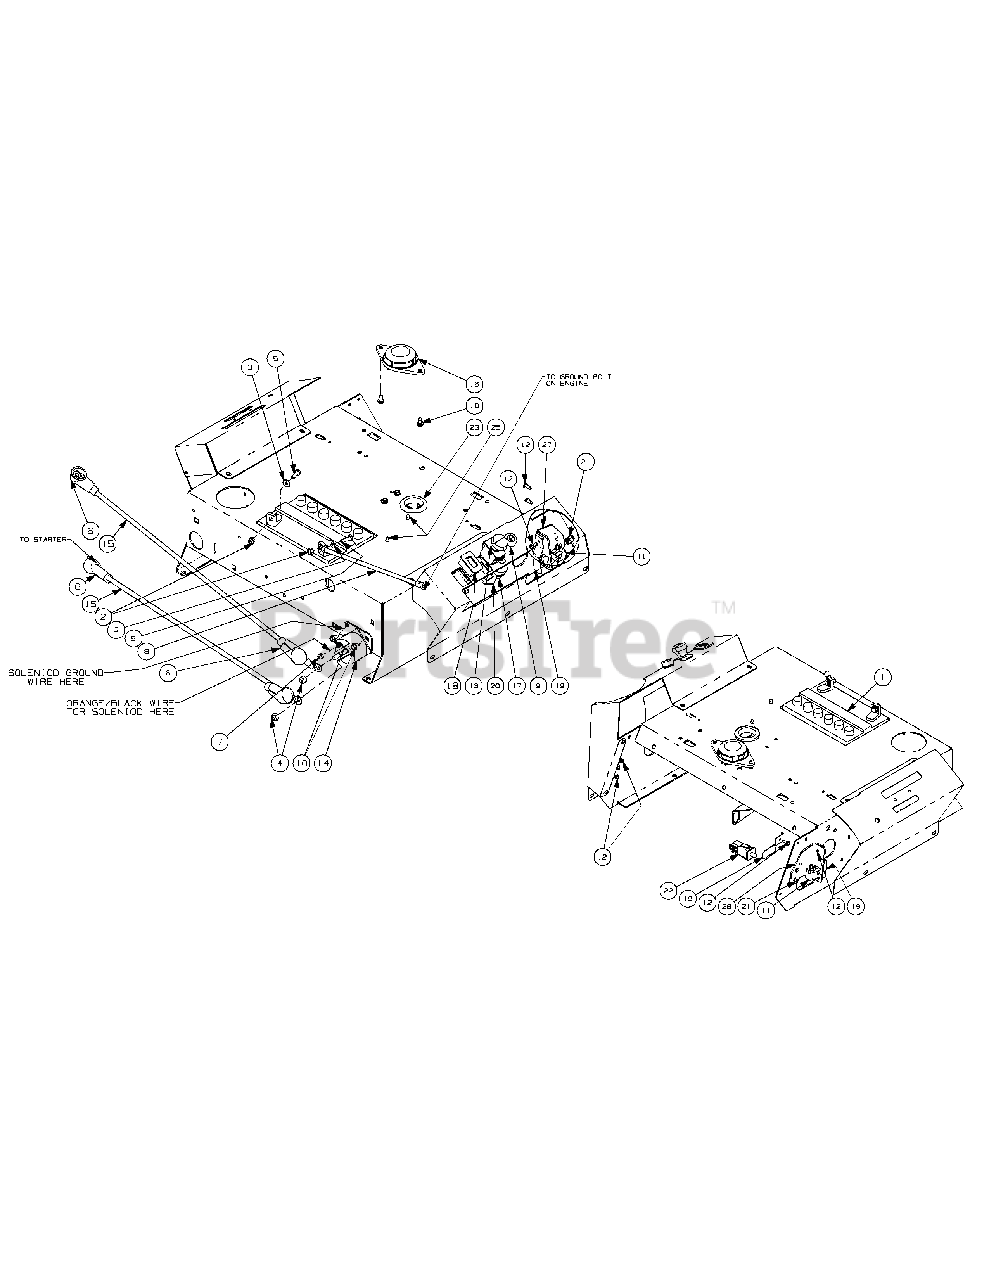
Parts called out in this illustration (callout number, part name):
1	Battery, 12V 225CCA 30Min
2	Lock Nut, Nylon Insert, 1/4-20
3	Flat Washer, 1/4
4	Nut, 5/16-18, Nylock
5	Hex Cap Screw, 1/4-20 x .75
6	Boot, 1" OD Rubber Battery-PST Red
7	Lock Nut, Nylon Insert, 10 - 32
8	Cable, Battery, Black, 17"
9	Nut, 5/8-32, w/Cap
10	Self Tapping Screw, 1/4-20 x 1/2
11	Normally Closed Safety Switch
12	Self Tapping Screw, 10-32 x 1/2
13	Electric PTO Switch
14	Solenoid Magnetic Switch
15	Cable, Battery, Red, 24"
16	Normally Closed Seat Switch
17	Switch, Ignition, 6 Pin
18	Hour Meter includes:
19	Safety Switch Retainer Spring
20	PTO Switch Bracket
21	U-nut, 10-24
22	Switch, Safety N.O./N.C.
23	Gromment, 1.5 ID x 2.13 OD
25	Electrical Conduit Clip, 1/2
27	Bracket, Safety Switch, Right Hand
28	Bracket, Safety Switch, Left Hand
